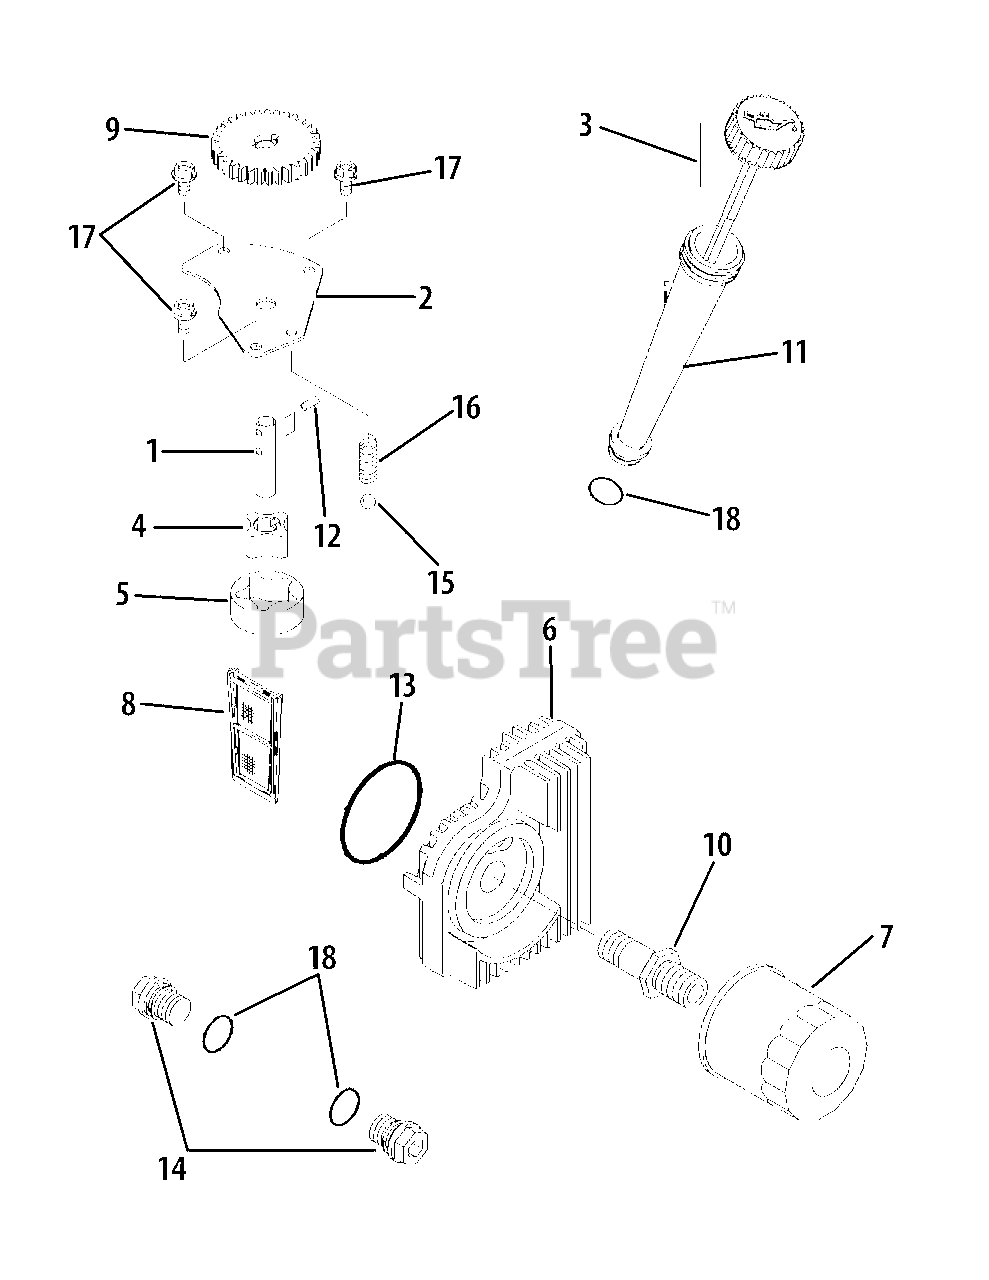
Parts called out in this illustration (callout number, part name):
1	Shaft
3	Dipstick Assembly
4	Pump Rotor (In)
5	Pump Rotor (Out)
6	Oil Cooler
7	Oil Filter
8	Oil Filter Screen
10	Joint
11	Dipstick/Oil Fill Tube
12	Pin
14	Plug
17	Flange Bolt
18	O-Ring, 16mm
